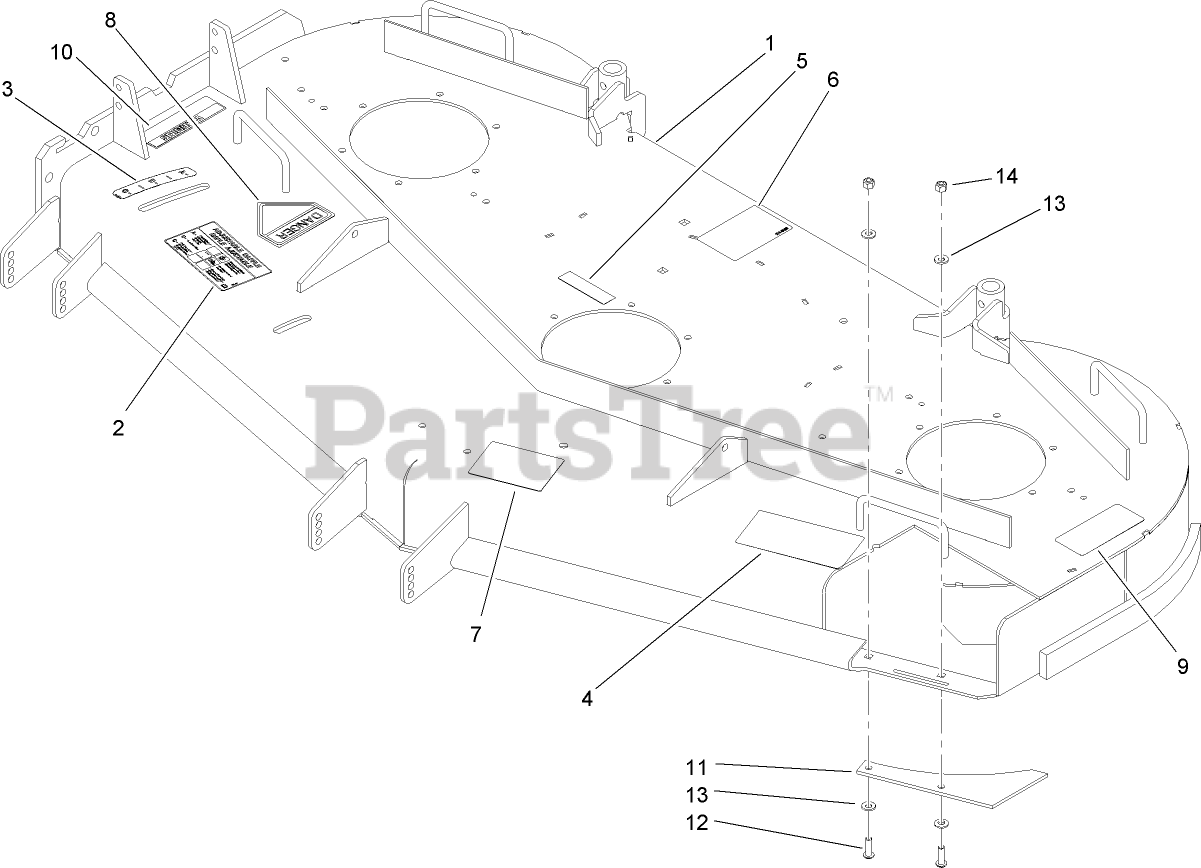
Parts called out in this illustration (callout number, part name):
1	Deck ASM
2	DECAL-ADJUSTMENT, BAFFLE
3	DECAL-SETTING, BAFFLE
4	DECAL-DANGER, THROWN OBJECT
5	DECAL-COVER, MISSING
6	DECAL-ROUTING, BELT
7	DECAL-SCALP, ANTI
8	DECAL-DANGER
9	DECAL-TORQUE
10	DECAL-WARNING
11	PLATE-TURBO
12	SCREW-HSBH
13	WASHER-SPRING
14	NUT-LOCK, NI
